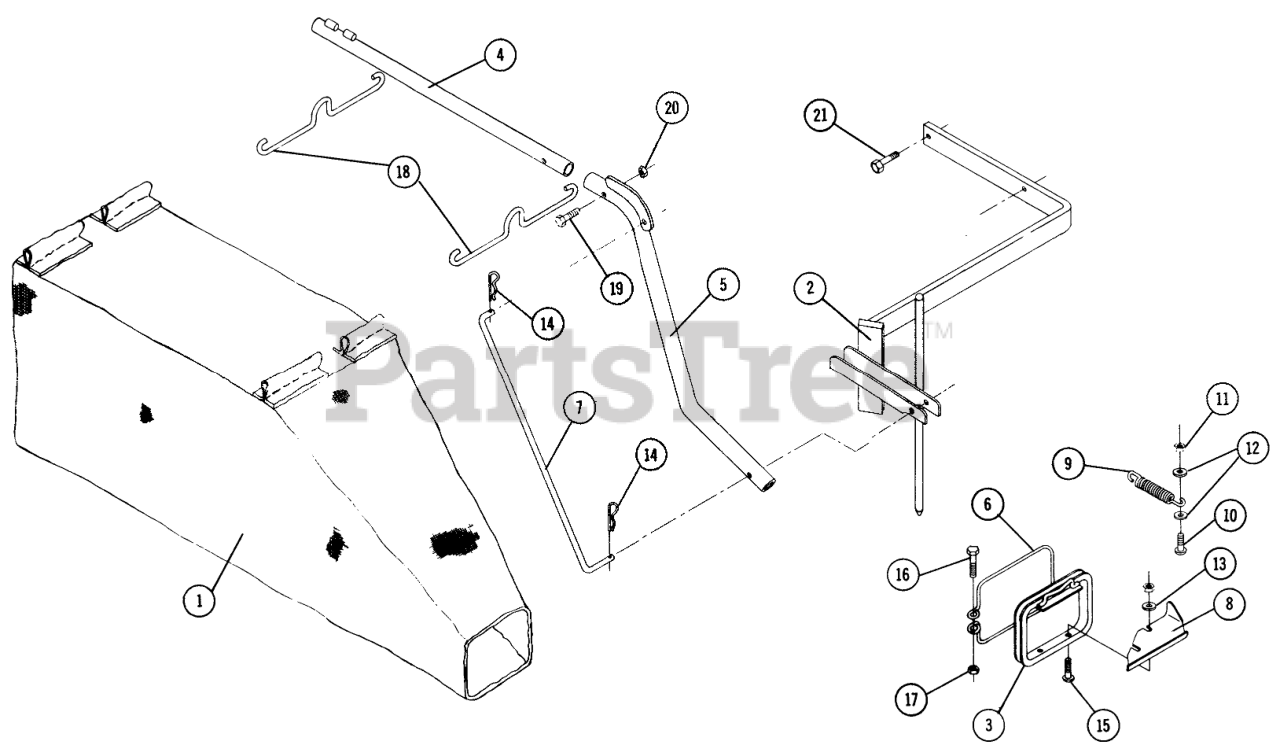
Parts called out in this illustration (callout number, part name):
2	Mounting Bracket
3	Bag Opening Frame
4	Upper Tube
5	Lower Tube
6	Hoop-Wire
7	Link
8	Bottom Plate
9	SPRING R
10	PAN HEAD SCREW-4
11	NUT
12	Washer
14	Hairpin Cotter
15	MACH. SCREW
16	Bolt 1/4-20 x 2
17	Nut
18	Hook
19	Bolt
20	Nut
21	Bolt, 3/8-16 x 1 1/4 Swage
